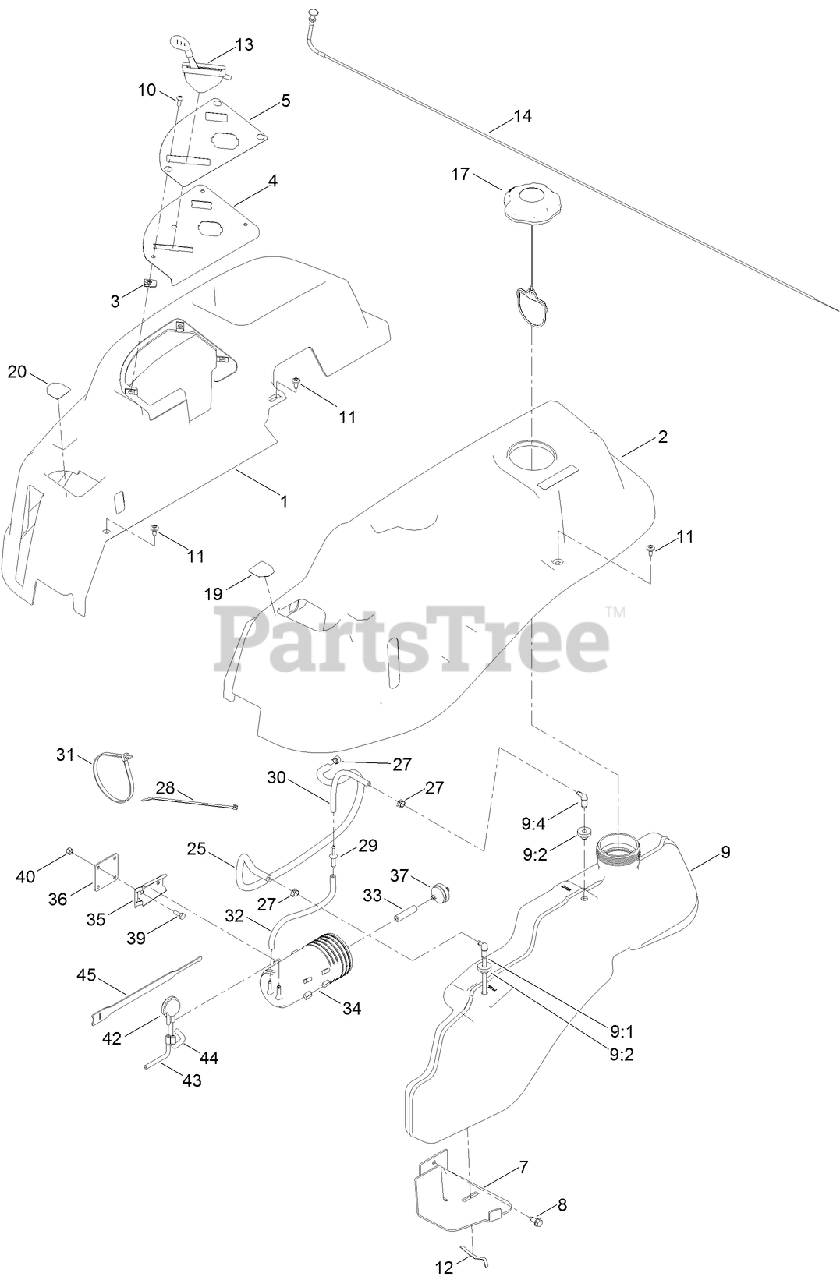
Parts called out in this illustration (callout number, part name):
1	POD-RH
2	POD-LH
4	PLATE-CONTROL
5	DECAL-PANEL, CONTROL
7	SUPPORT-TANK, FRONT
8	SCREW-HWHTF
9	FUEL TANK ASM
9:1	CONNECTOR-ELBOW, 90 DEG
9:2	BUSHING
9:4	FITTING-PLASTIC
10	SCREW-PRH
11	SCREW-SHOULDER
12	SPRING
13	CABLE-THROTTLE
14	CABLE-CHOKE
17	CAP-FUEL, RATCHETING
19	DECAL-LEVER, CONTROL (LH)
20	DECAL-LEVER, CONTROL (RH)
25	HOSE-FUEL
27	CLAMP-HOSE
28	TIE-CABLE
29	ADAPTOR-ORIFICE
30	HOSE-FUEL
31	TIE-CABLE
32	HOSE-FUEL
33	HOSE-FUEL
34	CANISTER-CARBON, 800CC
35	BRACKET-CANISTER, CARBON
36	PLATE-ADAPTER
37	FILTER-FUEL, INLINE
39	SCREW-HH
40	NUT-LOCK, NI
42	VALVE-CONTROL, VACUUM
43	HOSE-VENT, FORMED
44	HOSE-VENT, FORMED
45	STRAP-VELCRO, CABLE TIE
